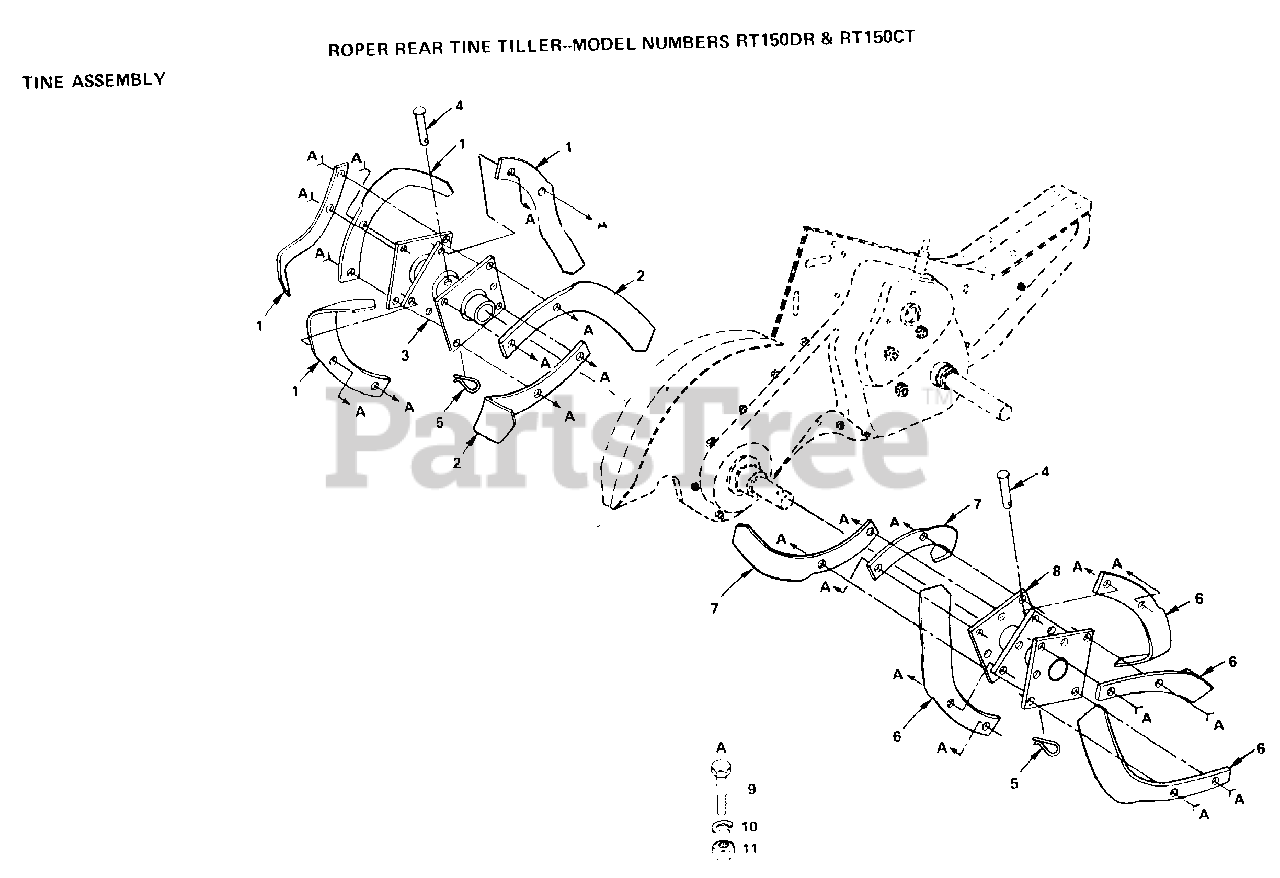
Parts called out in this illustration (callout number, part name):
2	"TINE.LH.12"""
3	TINE ASSY LH CRT
4	RIVET.PAN HD.1.75
5	RETAINER.SPRING
7	"TINE.RH.12"""
8	TINE ASSY RH CRT
9	BOLT
10	LOCKWASHER
